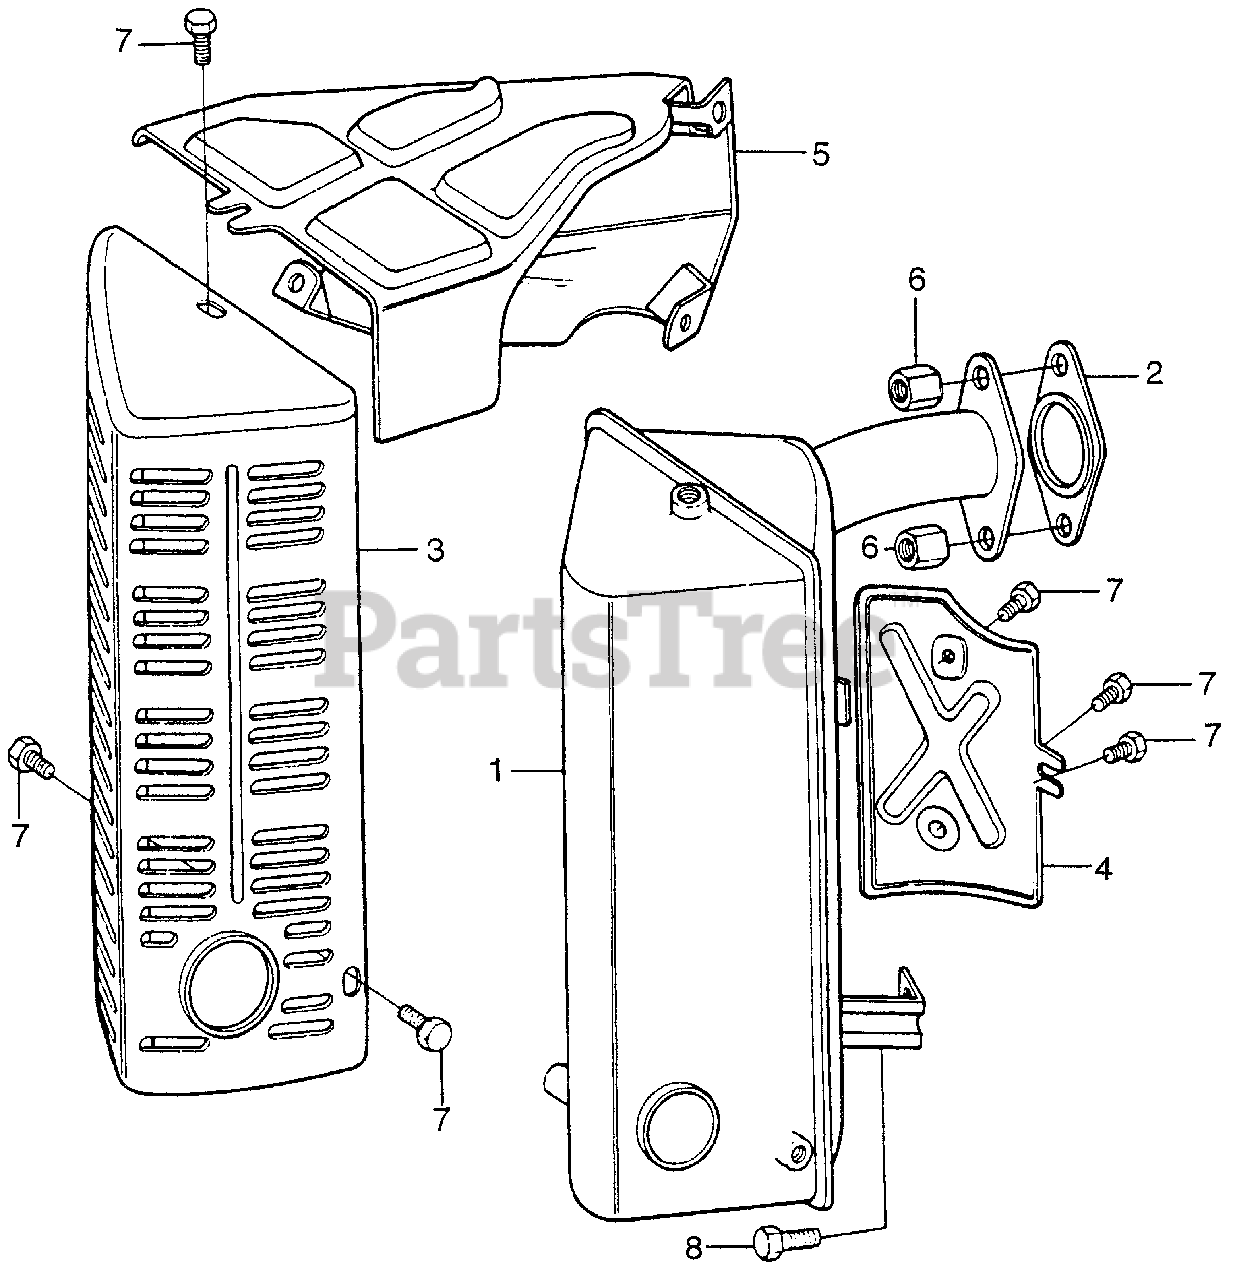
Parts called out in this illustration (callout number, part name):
1	MUFFLER (NOT AVAILABLE)
2	GASKET, MUFFLER (NOT AVAILABLE)
3	PROTECTOR, MUFFLER (NOT AVAILABLE)
4	PLATE, MUFFLER SEPARATOR
5	COVER, EX. PIPE
6	NUT, HEX. (6MM)
7	BOLT, HEX. (6X8)
8	BOLT, HEX. (8X18)
